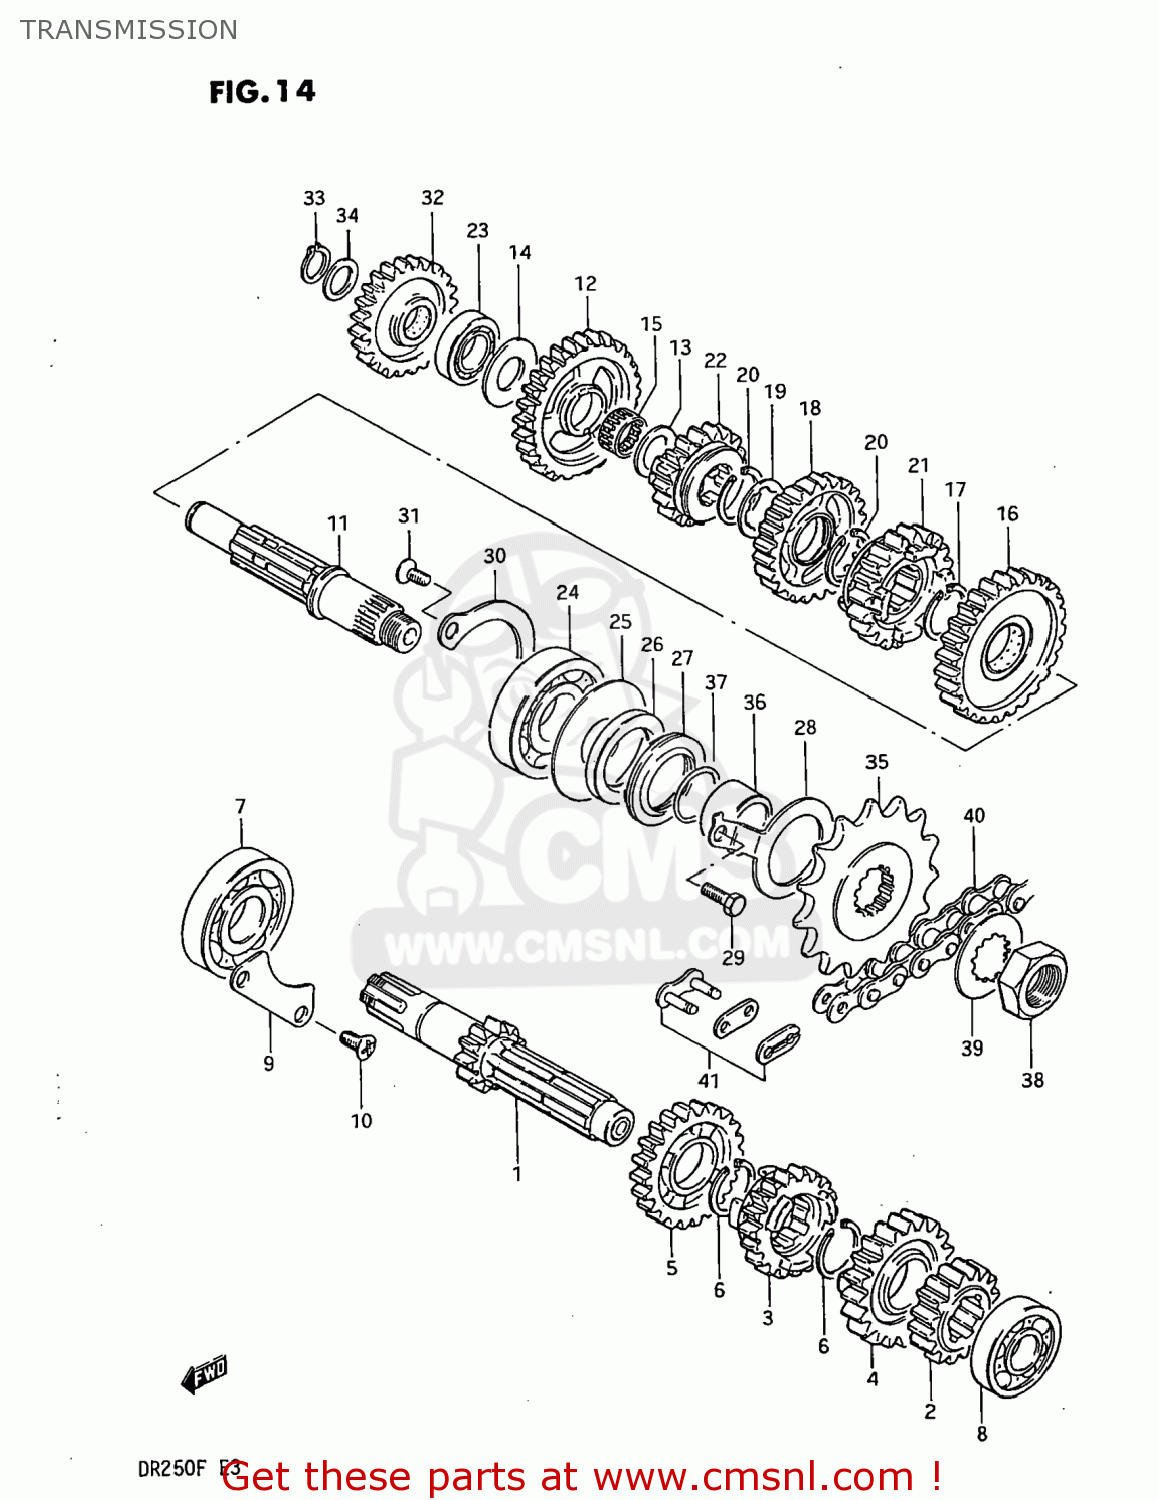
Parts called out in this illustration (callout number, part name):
1	SHAFT,COUNTER
2	GEAR,2ND DRIVE(NT:16)
3	GEAR,THIRD DRIVE (NT:19)
4	GEAR,FOURTH DRIVE
5	GEAR,FIFTH DRIVE
6	CIRCLIP
7	BEARING
8	BEARING
9	RETAINER,CNTR SHAFT BEARING
10	SCREW 6X12
11	SHAFT,DRIVE
12	GEAR,1ST DRIVEN(NT:29)
13	WASHER
14	WASHER
15	BEARING(17X21X9.8)
16	GEAR,SECOND DRIVEN
17	CIRCLIP
18	GEAR,THIRD DRIVEN
19	WASHER,LOCK
20	CIRCLIP
21	GEAR,FOURTH DRIVEN
22	GEAR,FIFTH DRIVEN
23	BEARING(17X36X12)
24	BEARING(22X56X16)
25	WASHER(35X55X1)
26	OIL SEAL (30X43X5)
27	OIL SEAL (30X43X7)
28	RETAINER,DRIVE SHAFT OIL SEAL
29	BOLT
30	RETAINER,DRIVE SHAFT BEARING
31	SCREW
32	GEAR,KICK STARTER IDLE(NT:24)
33	CIRCLIP
34	WASHER
35	SPROCKET,ENGINE
36	SPACER,ENGINE SPROCKET
37	O RING(D:2.5,ID:21)
38	NUT
39	WASHER,LOCK
40	CHAIN ASSEMBLY,DRIVE
41	JOINT ASSEMBLY,CHAIN
